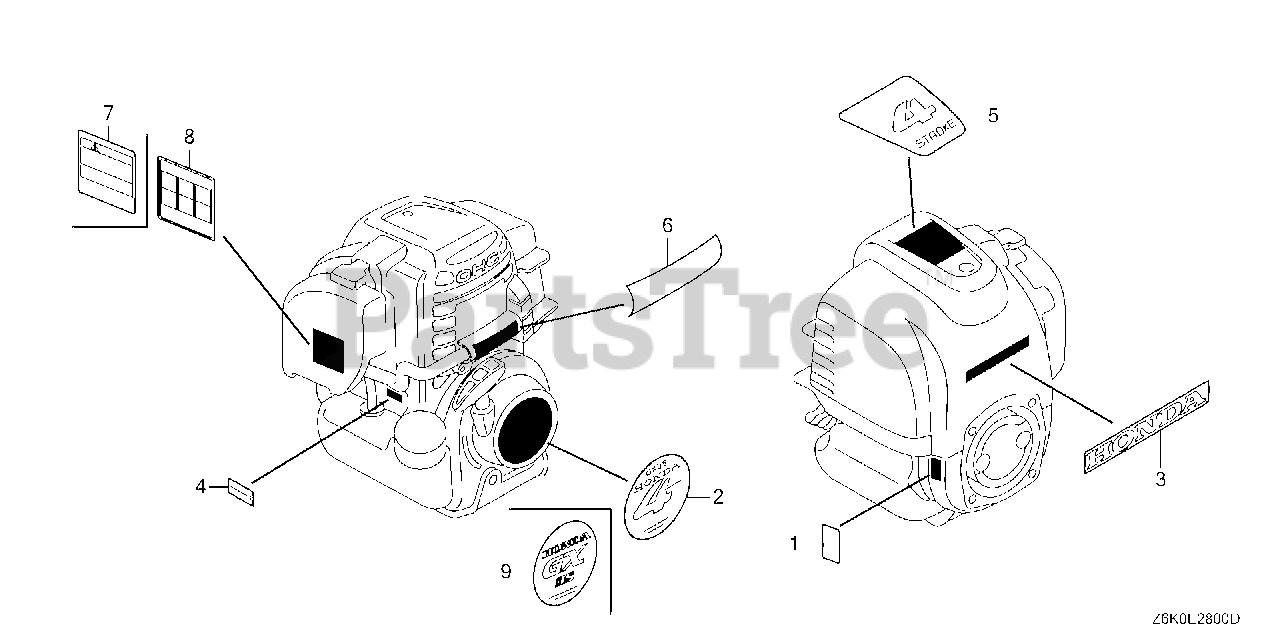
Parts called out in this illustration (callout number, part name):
1	LABEL, WARNING (NOT CERTIFIED FOR SALE)
3	MARK, HONDA
4	MARK, TYPE (TMS3)
5	MARK (4-STROKE)
7	MARK, OPERATOR CAUTION (ENGLISH)
8	MARK, OPERATOR CAUTION (PICTOGRAPH)
9	MARK, EMBLEM
